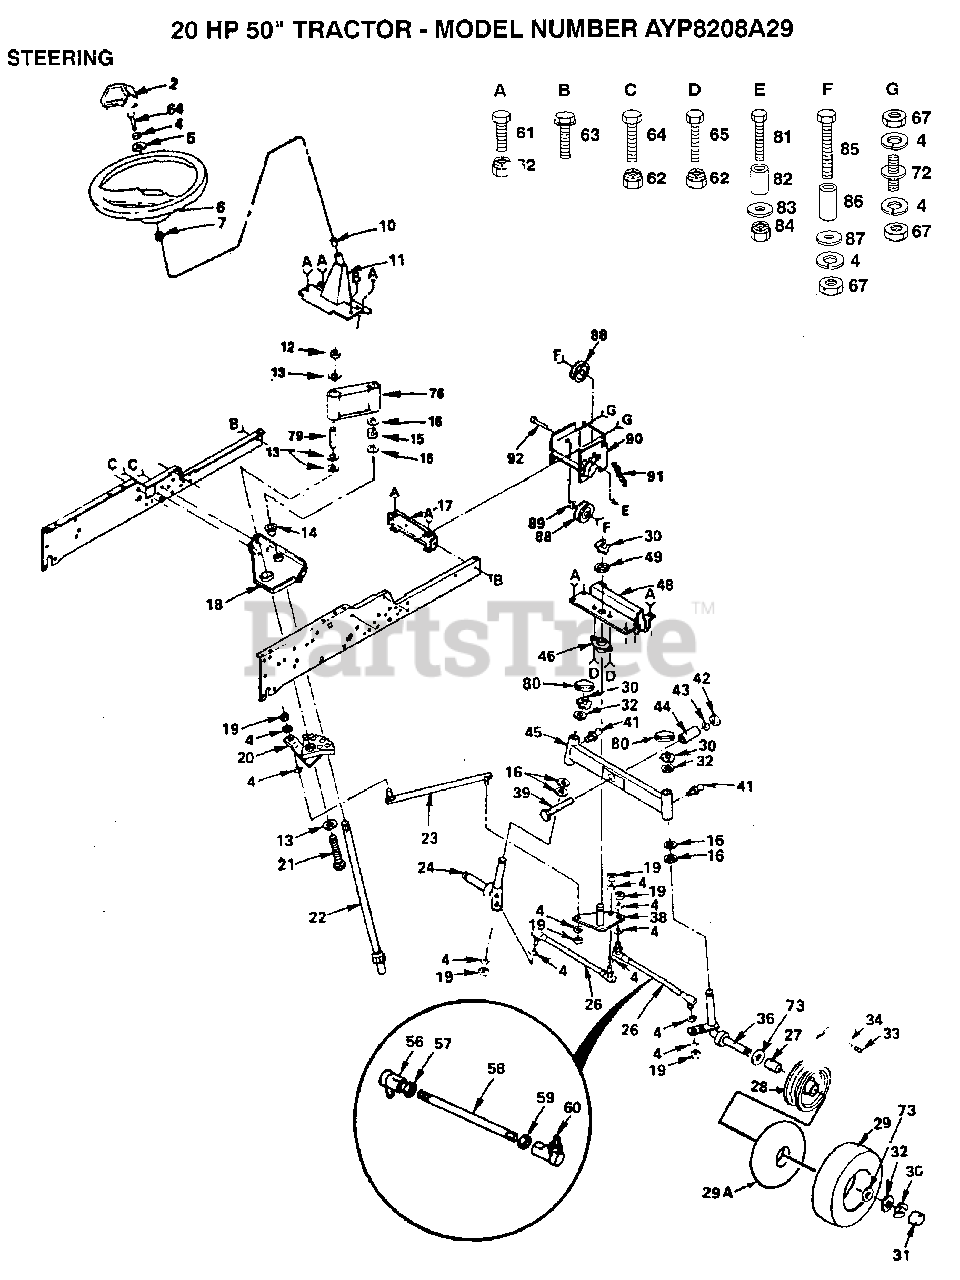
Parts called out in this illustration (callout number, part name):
2	"INSERT,STR WHEEL"
4	LOCKWASHER
5	WASHER T
7	ADAPTER LT
10	"T, BEARING"
11	SUPPORT ASSY T
12	NUT LTV
13	WASHER GT
14	"FLANGE GT, BEAR."
15	KLIP RING
16	WASHER .T
17	FRAME BRACKET GT
20	SECTOR T
21	BOLT T
22	SHAFT STEERING GT
23	LINK.DRAG.T
27	"FLANGE, BEARING"
29A	TUBE.16X6.5/7.5-8
30	RING
31	HUB CAP
32	WASHER
33	VALVE CAP
34	VALVE STEM LT
35	FITTING LT
38	"T, BELLCRANK"
39	BOLT
41	ZERK M
42	NUT X
43	WASHER
48	AXLE BRACKET T
49	WASHER
57	NUT
58	ROD TIE
59	NUT
63	SCREW
64	BOLT
65	BOLT
67	NUT.HEX.3/8-16UNC
73	WASHER
76	COLLAR
79	TUBE T
80	CAP
82	SPLIT SPACER YTV
83	WASHER
85	BOLT
86	BUSHING LT
87	WASHER
88	IDLER-INSIDE T
89	WASHER T
90	IDLER BRKT T
91	SPRING
